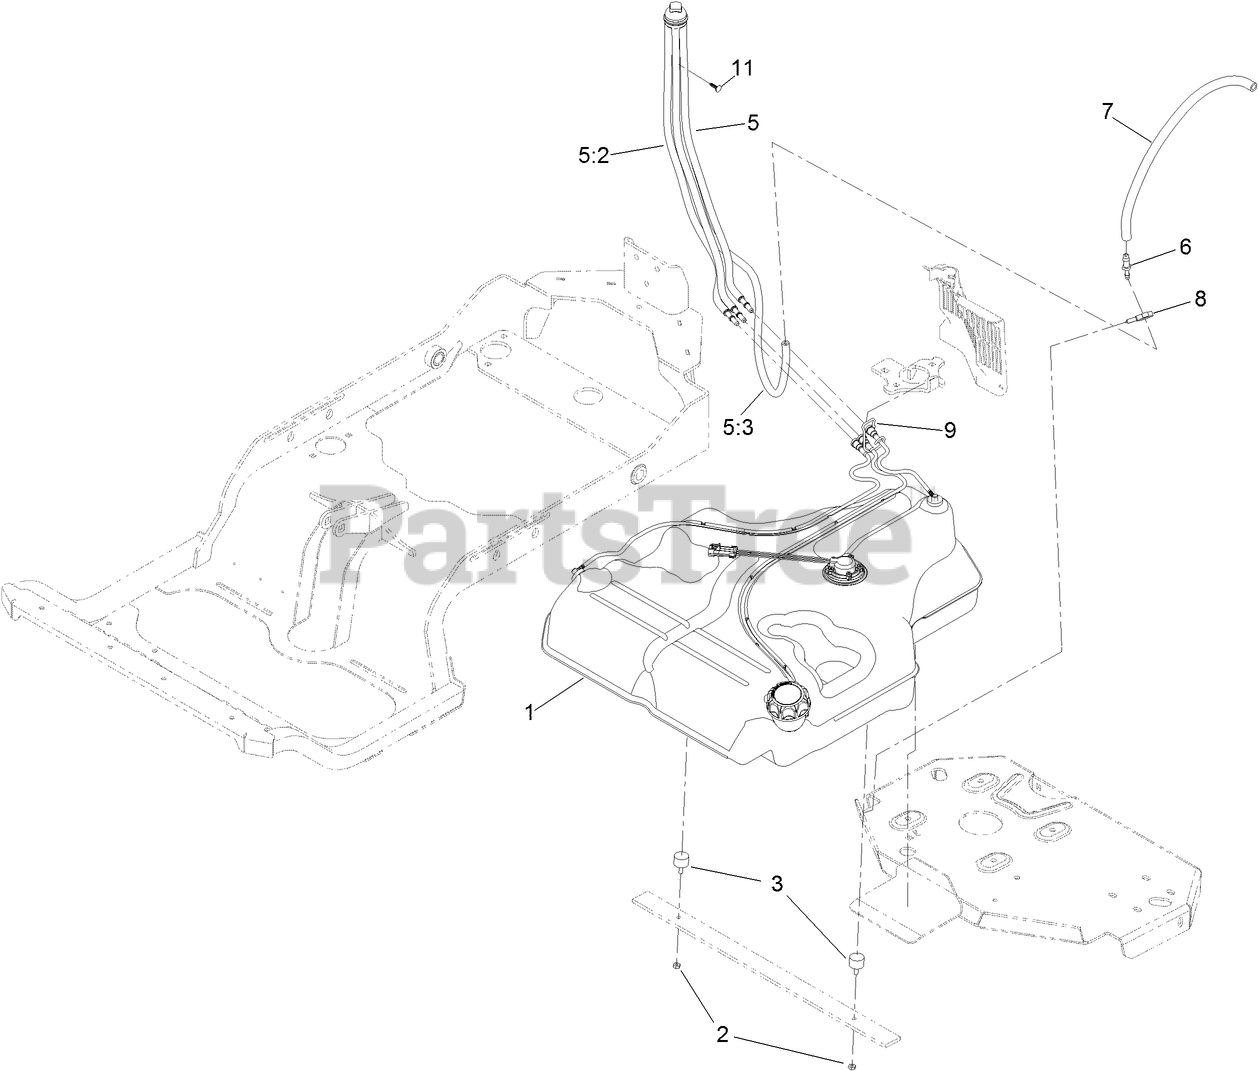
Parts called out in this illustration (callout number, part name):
1	FUEL TANK ASM
2	NUT-JAM
3	BUMPER
5	FUEL MANIFOLD VENT ASM
5:2	HOSE-FUEL
5:3	HOSE-FUEL
6	FITTING-STRAIGHT
7	HOSE-FUEL
8	CLAMP-HOSE
9	RETAINER-LINE, VAPOR
11	PLUG-PLASTIC
